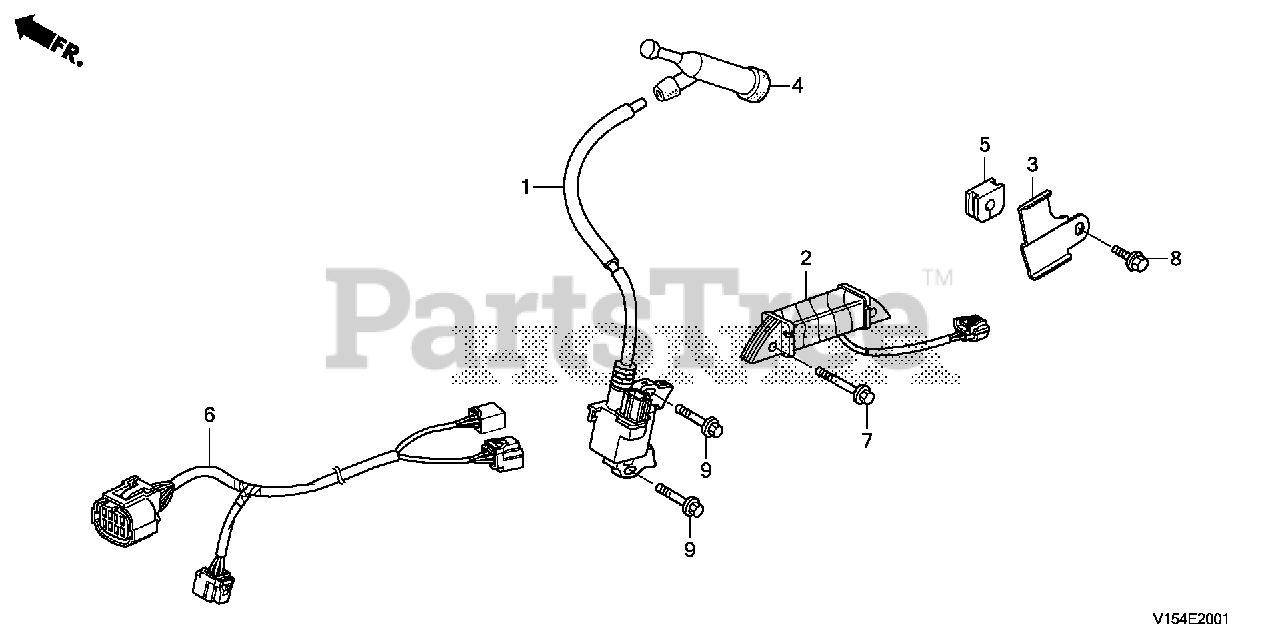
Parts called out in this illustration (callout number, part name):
1	COIL ASSY., IGNITION
2	COIL ASSY., POWER
3	BRACKET B, HARNESS
4	CAP ASSY., NOISE SUPPRESSOR (NGK Y-EZD)
5	GROMMET, WIRE
6	WIRE HARNESS ASSY., ENGINE
7	BOLT, FLANGE (6X35)
8	BOLT, FLANGE (6X12) (CT200)
9	BOLT, FLANGE (6X28) (CT200) Use up to Engine SN 1530314.
